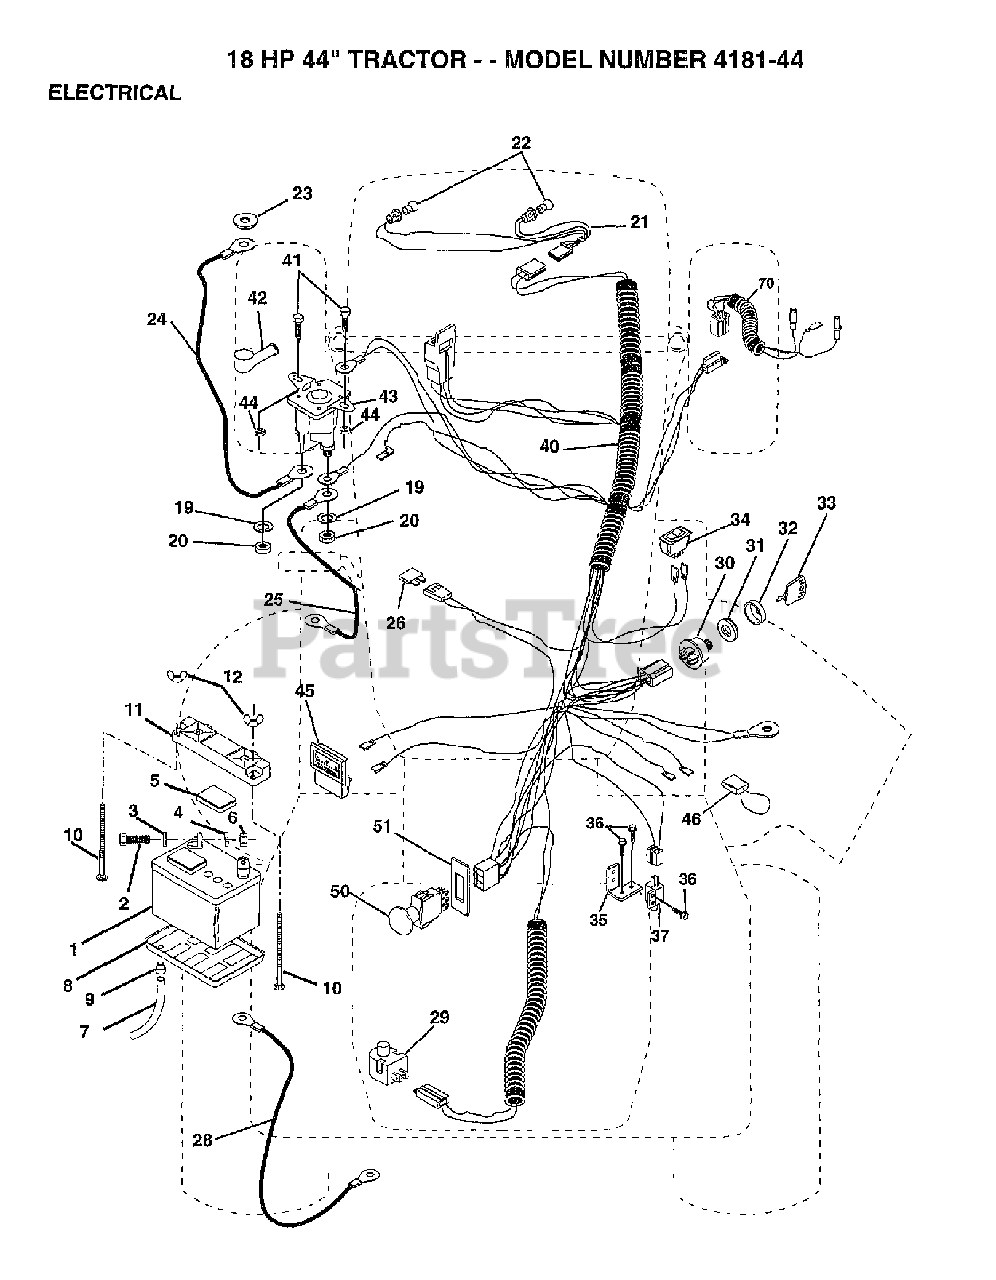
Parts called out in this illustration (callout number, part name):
1	BATTERY
2	BOLT.HEX.1/4.X.3/4.DICHROMATE
3	WASHER
4	LOCKWASHER
5	CAP BATTERY NLA
6	NUT
7	BATT DRAIN TUBE T
8	TRAY.BATTERY
9	HOSE CLAMP T
12	WING NUT
20	NUT
22	LIGHTBULB
23	LOCKWASHER
24	BATTERY CABLE
26	FUSE *
28	TIRE HEAVY DUTY
29	SWITCH SEAT
30	Ignition Switch Kit
31	NUT, IGNITION
32	COVER KEY IGNITIO
33	KEY MLD GEN DELTA
34	SWITCH LT
35	BRACKET LT
37	SWITCH-INTER. GT
41	BOLT
42	TERMINAL COVER
43	Solenoid Kit, .95
44	NUT.CROWNLOCK.1/4
46	WIRE PROTECTION LOOP
50	SWITCH-PTO
51	RETAINING RING
